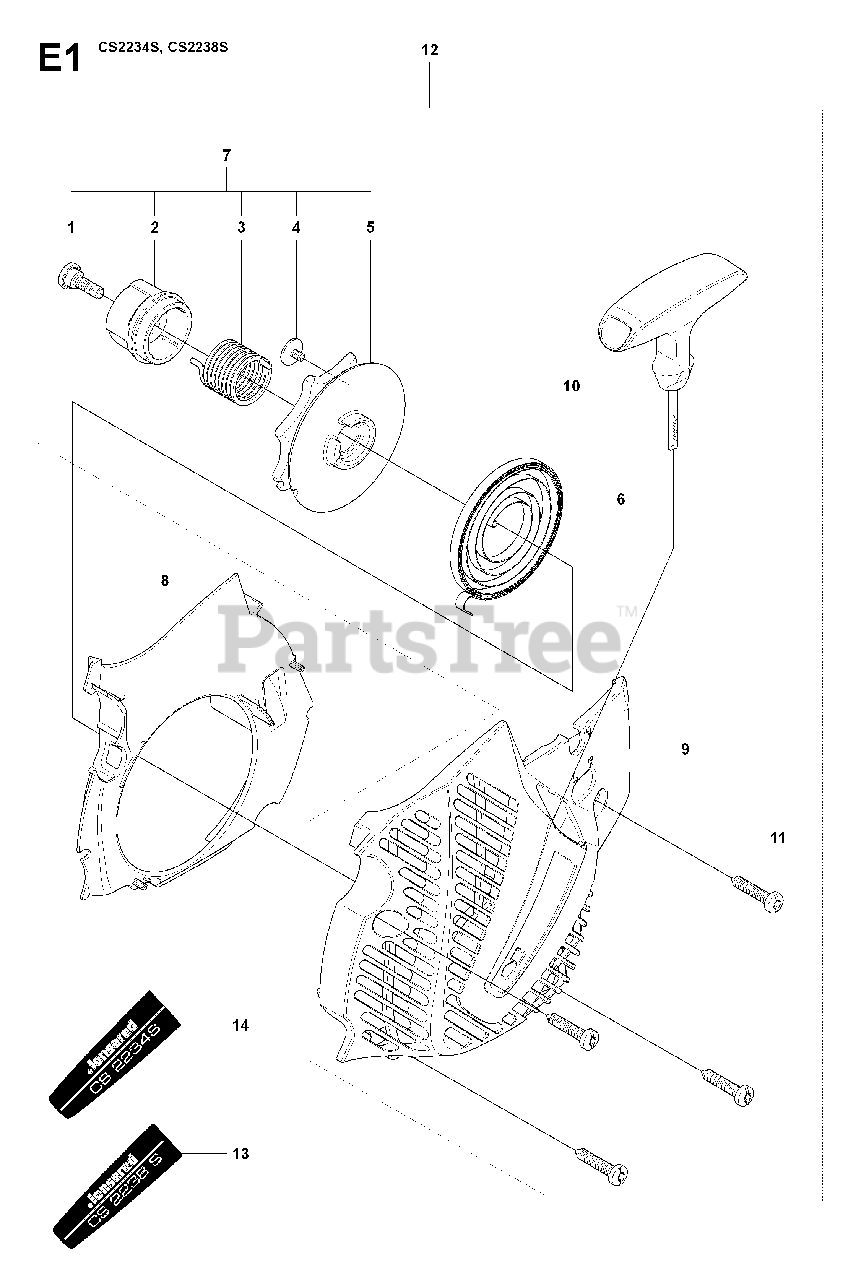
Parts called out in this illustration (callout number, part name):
1	SCREW SHOULDER
2	HUB STARTER EPS
3	SPRING EPS
4	SCREW
5	PULLEY STARTER EPS
6	SPRING STARTER
7	KIT EPS STARTER
11	SCREW M5.38-14X22.225MM
14	DECAL 240E
